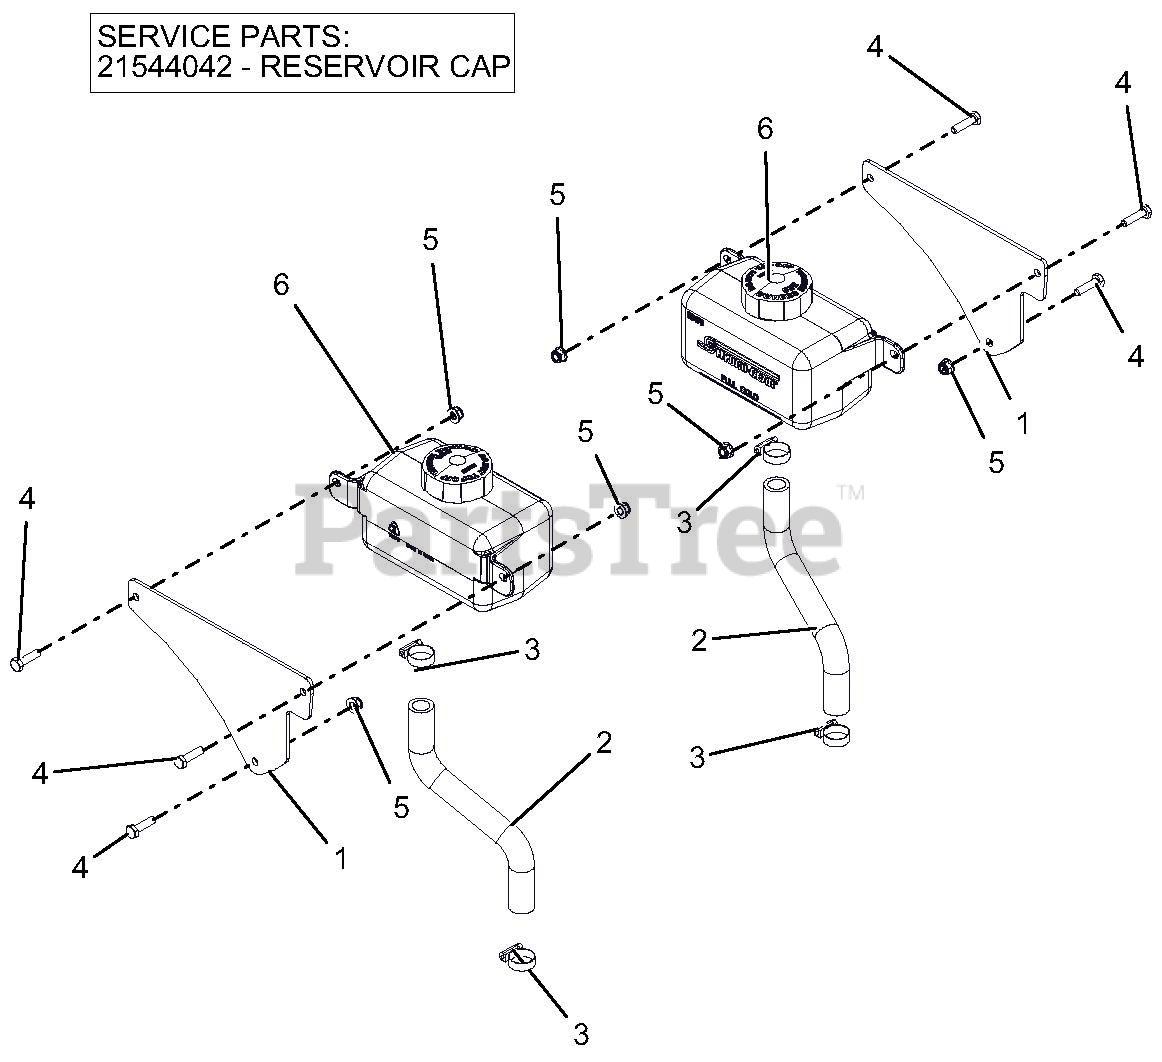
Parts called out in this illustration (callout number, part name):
1	PLATE, HYDRO OVERFLOW TANK MTG
2	HOSE, HYDRO OVERFLOW
3	CLAMP, .88 DIA HOSE
4	BLT-HEX .25-20X1.00 GR5 YWZC
5	NUT-LK-NYL-FLG .25-20 YWZC
6	TANK, HYD 1000ML
7	RESERVOIR CAP
